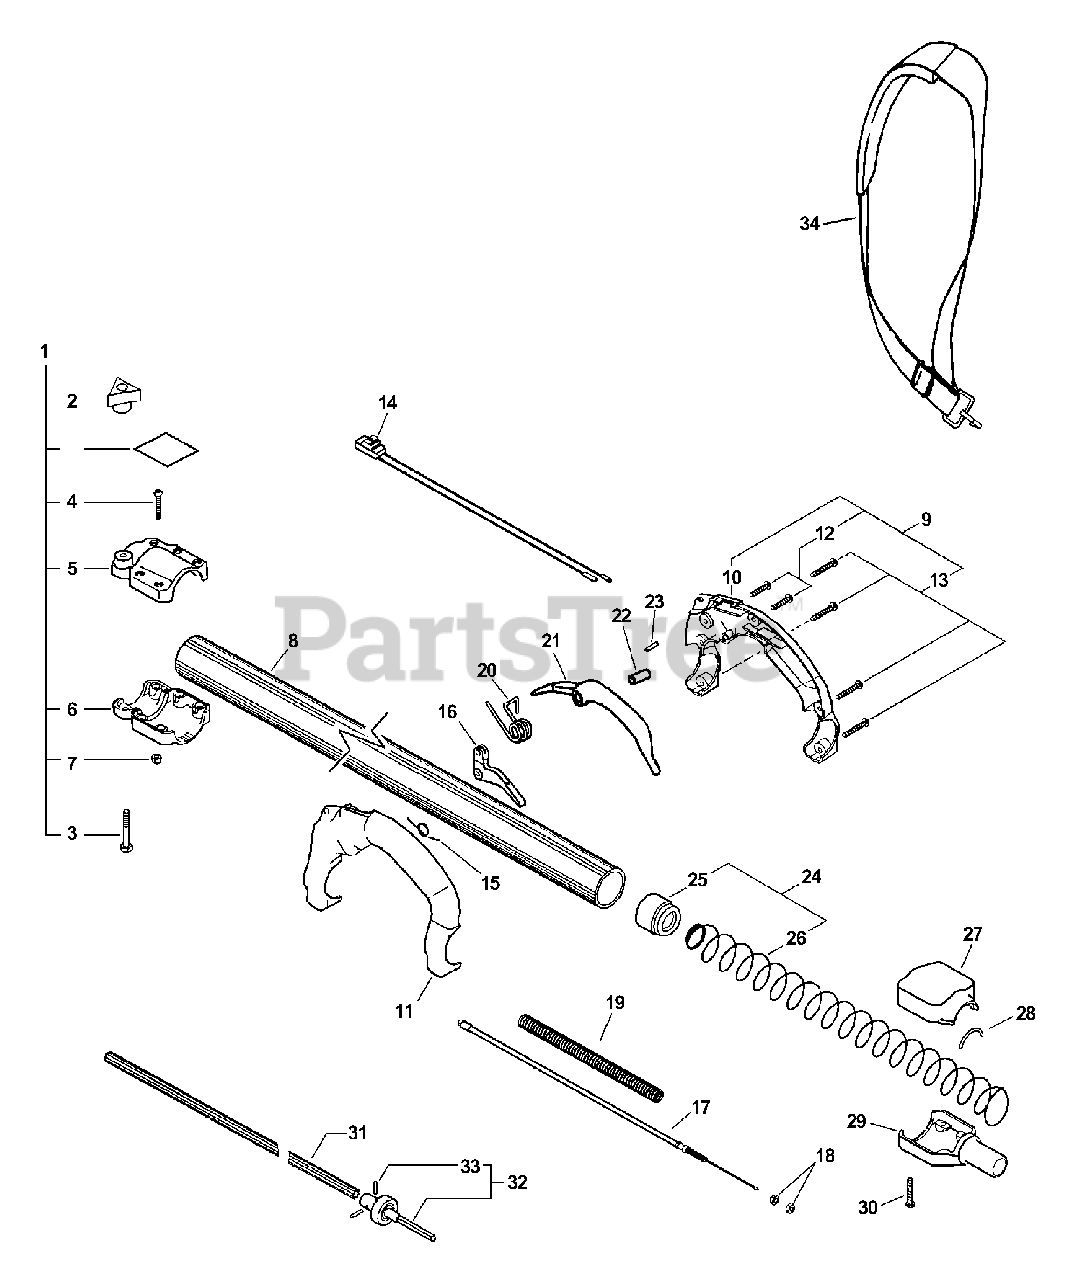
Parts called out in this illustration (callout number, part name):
1	CLAMP ASSY
2	THUMBSCREW
3	SCREW
4	SCREW, TORX 10-24 UNC 1-1/4
5	COLLAR, UPPER
6	COLLAR, LOWER
7	NUT, LOCK 10-24 UNC
8	PIPE, MAIN 1.5 ID×60" L
9	REAR HANDLE ASSY
10	HANDLE, REAR - RIGHT
11	HANDLE, REAR - LEFT
12	SCREW, TORX
13	SCREW, TORX 10-24 UNC 1-1/4
14	SWITCH ASSY, ON-OFF
15	SPRING, TORSION
16	TRIGGER, THROTTLE
17	CABLE, THROTTLE
19	TUBE, FLEXIBLE
20	SPRING, TORSION Ø0.39 I.D.
21	LOCKOUT, THROTTLE
22	COLLAR 5.08×14.5
23	PIN, LOCATING 0.17 OD×0.75 L
24	BUSHING ASSY, FLOATING
25	BUSHING, FLOATING
26	SPRING, COMPRESSION
27	CAP, MAIN PIPE
29	COUPLING, MAIN PIPE
30	SCREW, TORX 10-24 UNC 1-1/4
31	DRIVESHAFT
32	SHAFT CONNECTOR KIT
33	PIN 0.098"×0.687"
34	STRAP ASSY, SHOULDER
